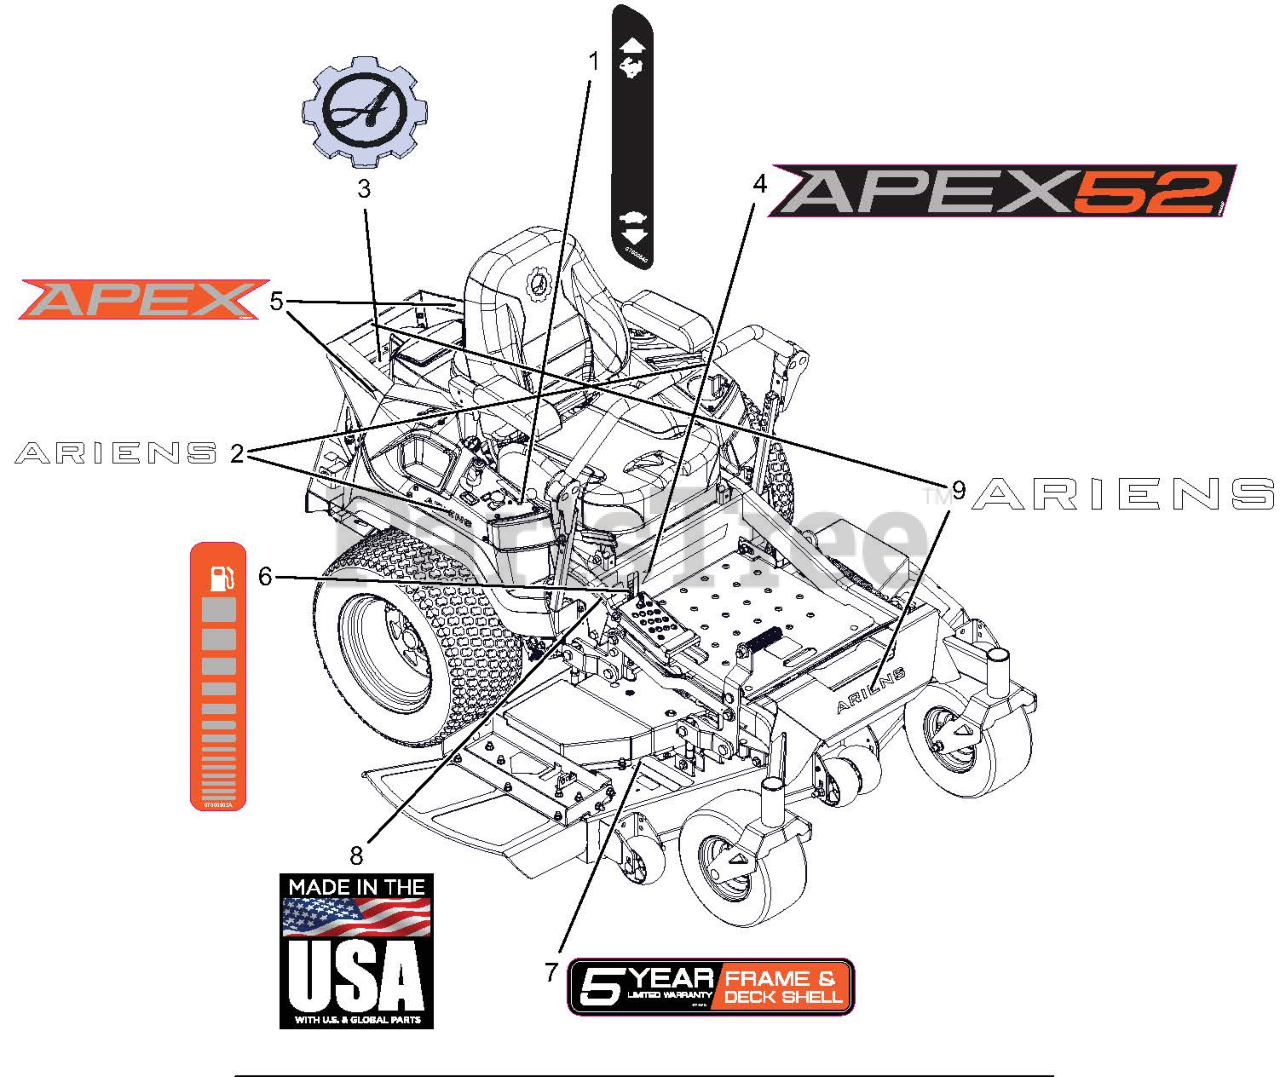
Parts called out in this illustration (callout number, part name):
1	DECAL, DASH DECAL
2	DECAL, ARIENS (6.50")
3	DECAL, ARIENS-GEAR BADGE -THK
4	DECAL, 52" APEX KICKPLATE
5	DECAL, APEX FENDER
6	DECAL, ARIENS FUEL LEVEL
7	DECAL, DECK 5 YEAR-ARIENS
8	DECAL, MADE IN USA
9	DECAL - ARIENS 9.625"
